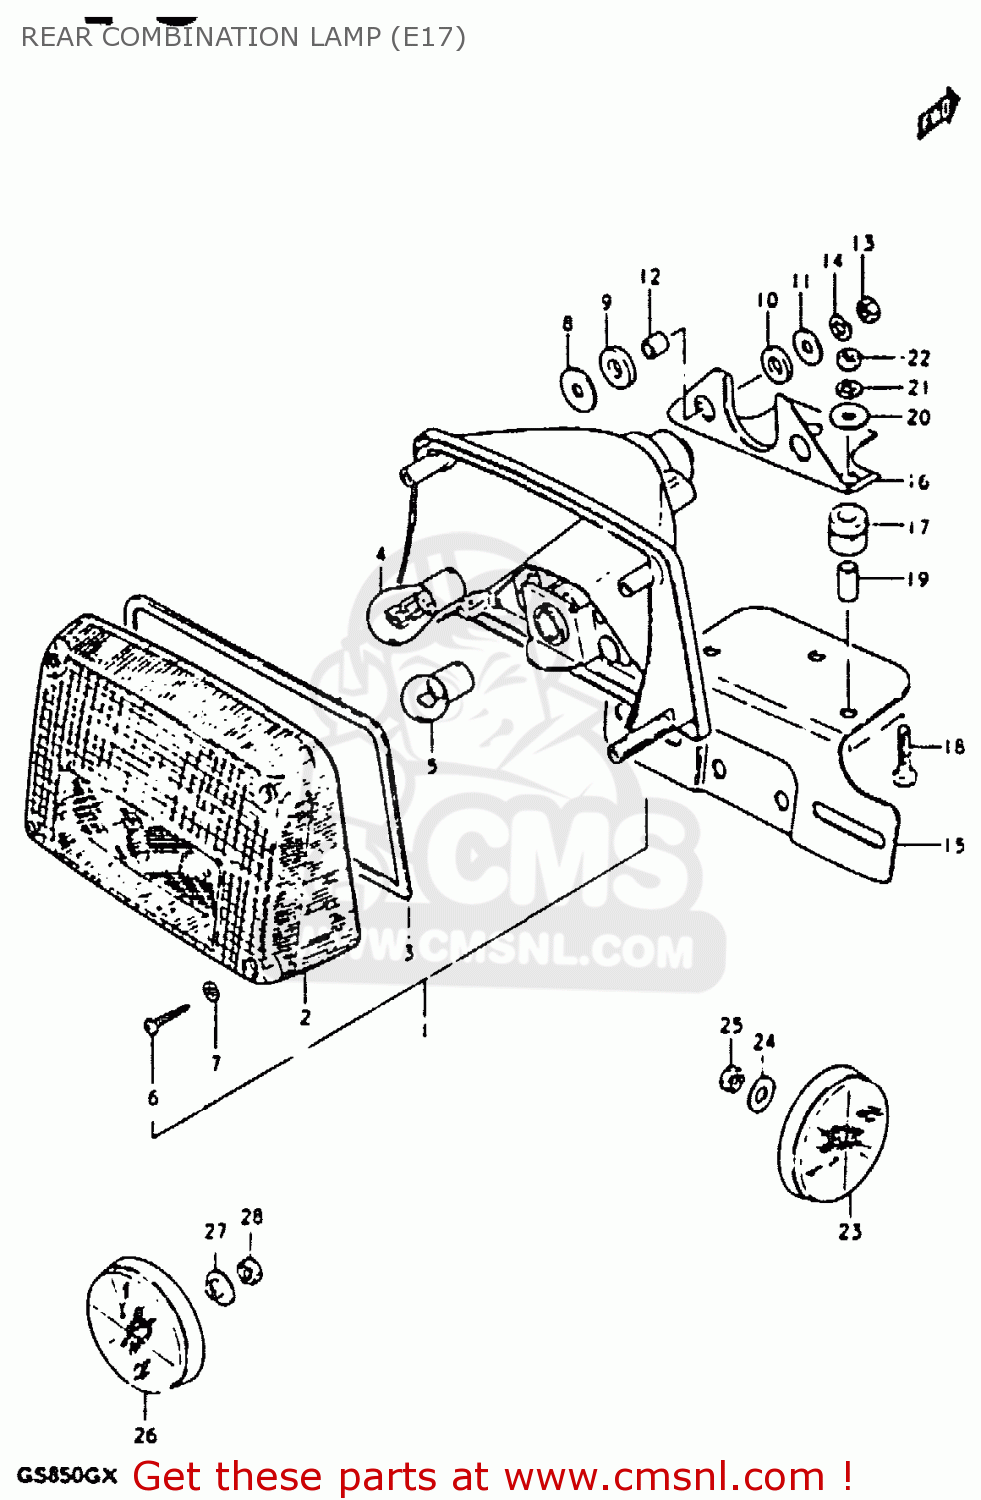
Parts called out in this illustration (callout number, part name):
1	LAMP, REAR COMBINATION
2	LENS
3	GASKET (NAS)
4	BULB 12V21/5W
5	BULB
6	BOLT
7	GASKET (NAS)
8	WASHER
9	CUSHION
10	CUSHION
11	WASHER(6,5X22X1.6)
12	SPACER(6.1X9X7.5)
13	NUT
14	LOCK WASHER
15	BRACKET, LICENCE PLATE
16	BRACKET,LICENSE PLATE
17	CUSHION, BRACKET
18	BOLT
19	SPACER (6.4X9X15.5)
20	WASHER
21	LOCK WASHER
22	NUT
23	REFLEX REFLECTOR,RR
24	WASHER
25	NUT
26	REFLEX REFLECTOR,RR
27	SPACER
28	NUT
